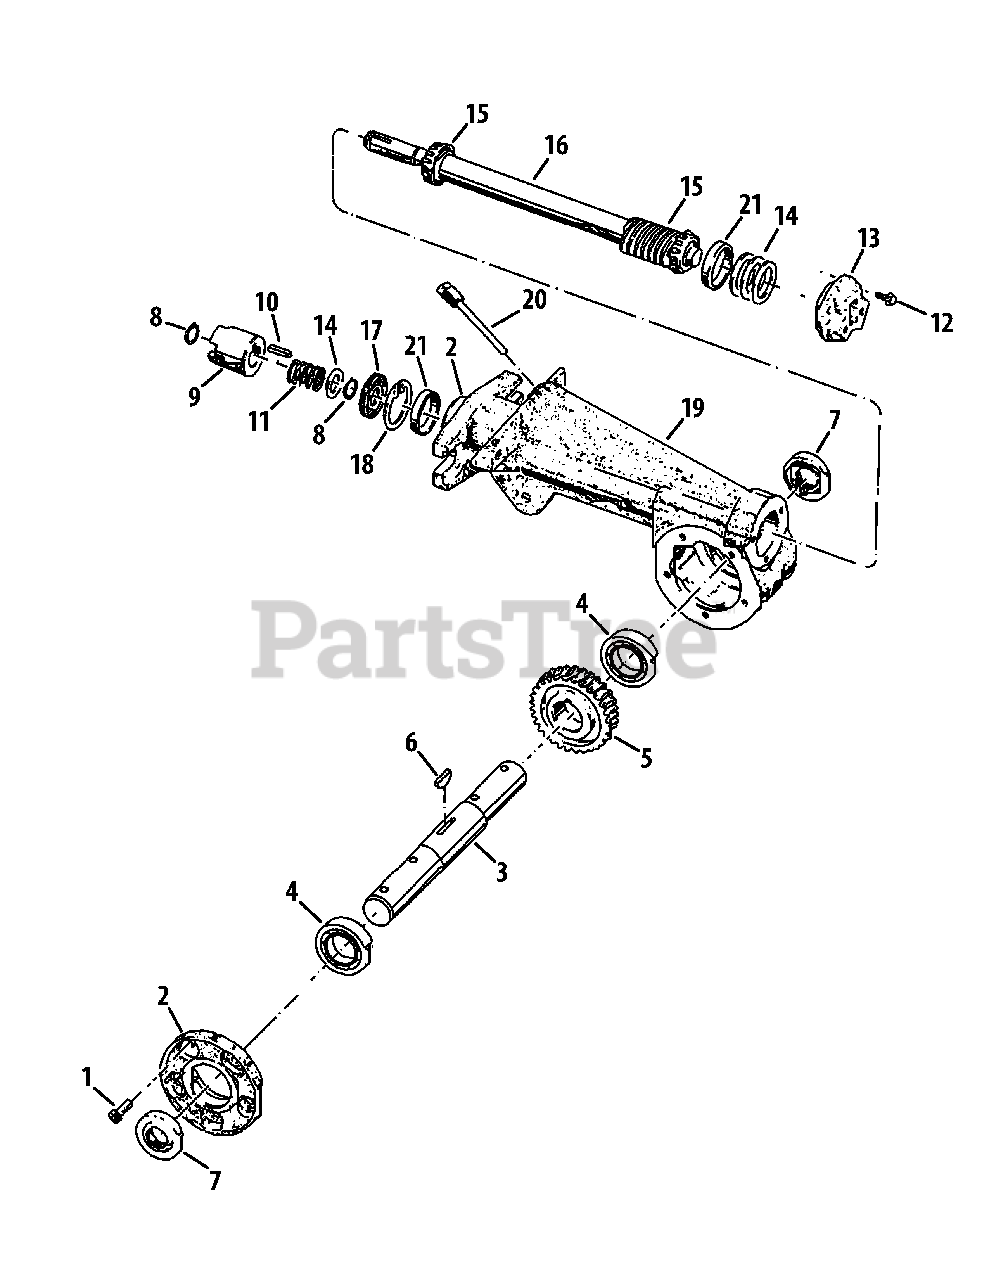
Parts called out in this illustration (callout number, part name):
1	Self-Sealing Screw, 1/4"-20 x 5/8"
2	Tiller Housing Cover
3	Tine Shaft
4	Ball Bearing
5	Worm Gear
6	Woodruff Key
8	External Retaining Ring
9	Dog Clutch
10	Key, 3/16" x 1"
12	Self-Sealing Screw, 1/4"-20 x 7/8"
14	Flat Washer, 1.75 x 1.5 x .062
14	Flat Washer, 1.75 x 1.5 x .005
14	Flat Washer, 1.75 x 1.5 x .03
14	Flat Washer, 1.75 x 1.5 x .01
15	Cone Bearing
18	Retaining Ring
19	Attachment Housing
20	Oil Dipstick
21	Cup Bearing
